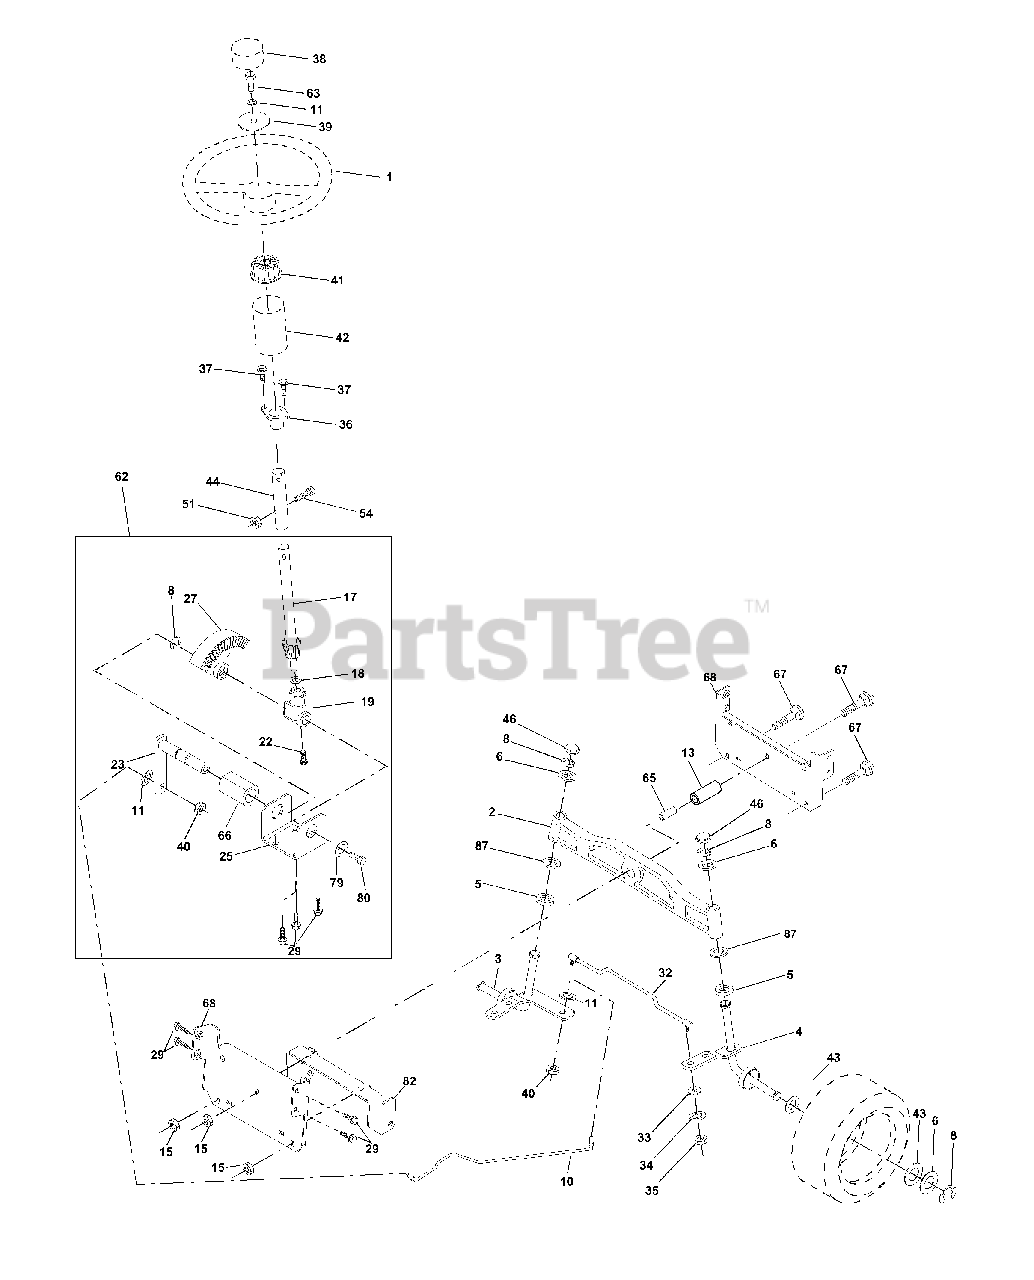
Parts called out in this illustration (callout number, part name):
1	Wheel Steering
2	Axle Asm Cast Iron LT
3	Spindle Asm LH
4	Spindle Asm RH
5	Bearing Race Thrust Harden
6	Washer 25/32 X 1-5/8 X 16 Ga
8	Ring Klip #t5304-75
10	Link Drag
11	Washer Lock Hvy Hlcl Spr 3/8
13	Spacer Brg Axle Front
15	Nut Hex Flange Lock
17	Shaft Asm Strg
18	Washer Thrust
19	Support Shaft Steering
22	Screw Hex Wshhd Torx
23	Shaft Asm Pittman
25	Bracket Steering
27	Gear Sector
29	Screw 3/8-16 x .75
32	Rod Tie
33	Washer 11/32 x 3/4 x 16 Ga
34	Washer Lock Hvy Hlcl Spr 5/16
35	Crownlock Nut 5/16-24 Unf
36	Bushing Strg
37	Screw
38	Insert Cap Strg Wh
39	Washer 13/32 X 1-1/2 X 11 Ga
40	Lock nut
41	Adaptor Wheel Strg
42	Boot Steering Dash
43	Washer 25/32 X 1 1/4 X 16 Ga
44	Extension Steering Shaft LR/LT
46	Cap Spindle Fr Top Blk
51	Nut Lock Hex w/Ins 5/16-18
54	Bolt Fin Hex 5/16-18 Unc x 1-1/4
62	Kit Steering Asm Service
63	Bolt Fin Hex 3/8-16unc x 1 Gr. 5
65	Spacer Brace Axle
66	Bearing Arm Pittman
67	Bolt Rdhd Sq 3/8-16 Unc x 2-3/4
68	Axle, Brace
79	Washer 13/32 x 1-1/4 x 12 Ga
80	Bolt Hex Nylon 3/8-16 x 3/4
82	Bracket Susp Chassis Front
87	Washer Flat .781 x 1-1/2 x .14
